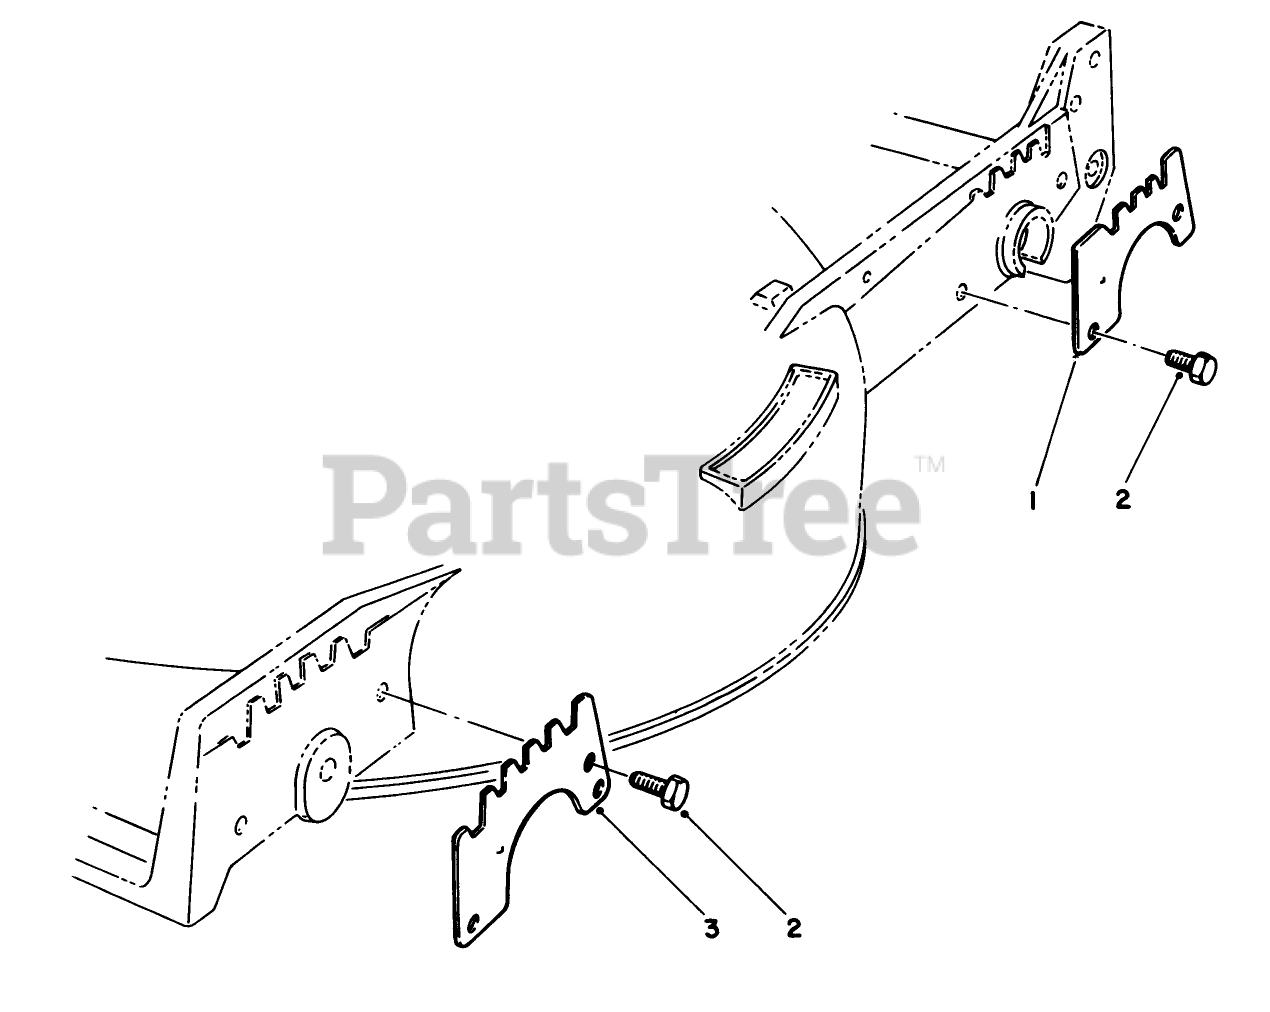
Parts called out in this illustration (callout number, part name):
1	WEAR PLATE,REAR
2	SCREW-HWH
3	WEAR PLATE
